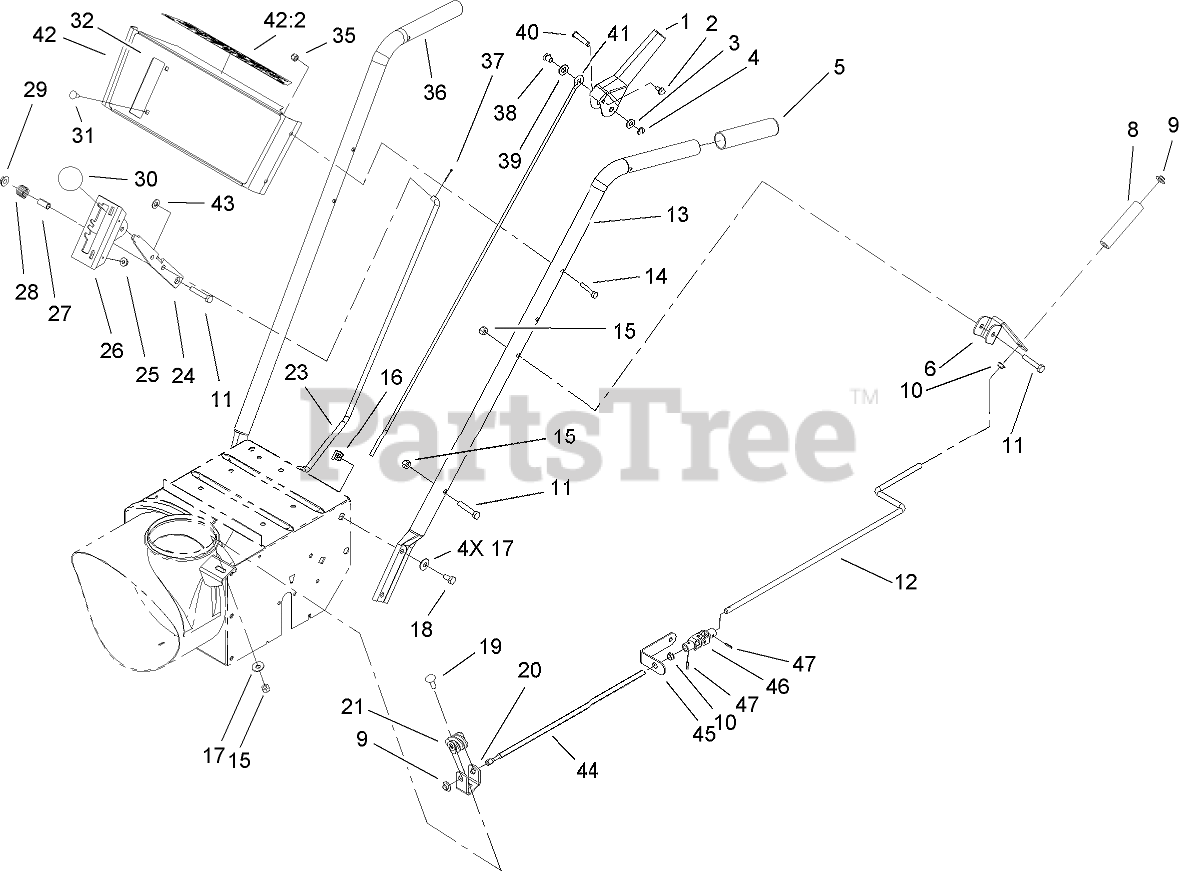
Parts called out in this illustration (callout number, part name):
1	HANDLE-CONTROL
2	SCREW-HHF
3	WASHER-PLAIN
4	RING-CLIP
5	GRIP-HANDLE
6	BRACKET-ROD, UPPER CHUTE
8	GRIP-CONTROL, CHUTE
9	RETAINER-PUSH ON
10	Bushing
11	SCREW-HH
12	ROD-CHUTE, UPPER
13	HANDLE-LEFT
14	SCREW-HH
15	NUT-LOCK, NI
17	WASHER-BELLEVILLE
18	SCREW-HH
19	SCREW-CARR
20	BRACKET-WORM
21	GEAR-WORM, CHUTE
23	ROD-SELECTOR, SPEED
24	Selector-Speed
25	NUT-HF
26	MOUNT-SELECTOR, SPEED
27	SPACER
28	SPRING
29	NUT-HF
31	SCREW-CARR
32	DECAL-ESCUTCHEON
35	NUT-LOCK, NI
36	HANDLE-RIGHT
37	PIN-COTTER
38	POST-MOUNTING, LINKAGE
39	WASHER-FLAT
40	PIN-LEVER, CONTROL
41	LINK-UPPER
42	ESCUTCHEON PANEL ASM
42:2	DECAL-ESCUTCHEON, BACK
43	WASHER-PLAIN
44	ROD-CHUTE, LOWER
45	BRACKET-ROD, LOWER
46	JOINT-UNIVERSAL
47	PIN-ROLL
